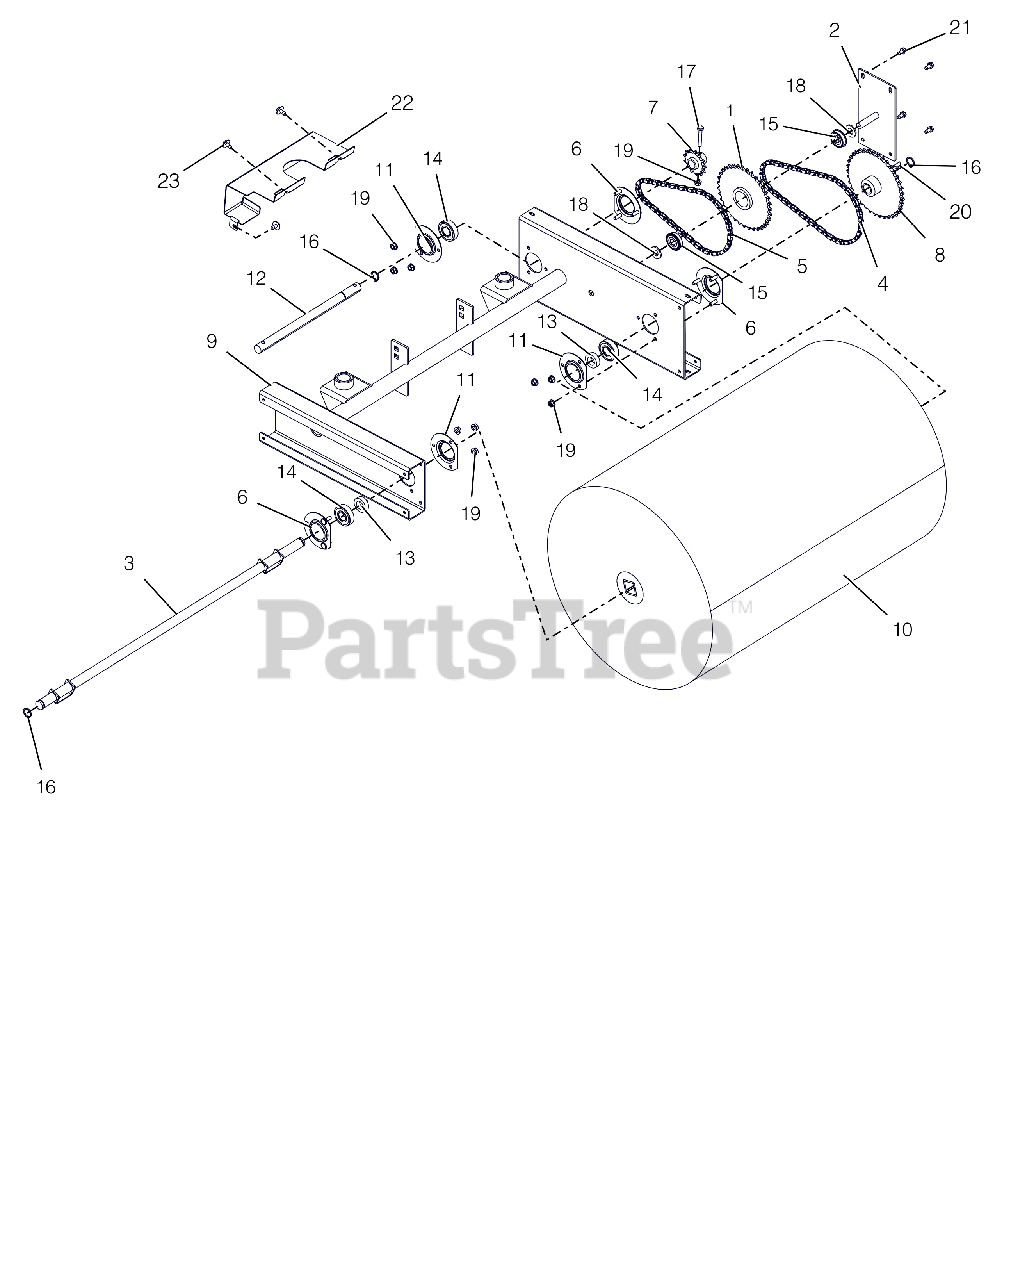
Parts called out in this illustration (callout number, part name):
1	SPROCKET, REDUCTION IDLER
2	PLATE, IDLER REDUCTION MOUNT
3	SHAFT, 28" BRUSH
4	CHAIN, #40-54 LINKS
5	CHAIN, #41-50 LINKS
6	BEARING FLANGE
7	SPROCKET, DRIVE
8	SPROCKET, DRIVEN
9	FRAME, POWER BROOM-DELUXE
10	BRUSH, 18"DIA X 28"WIDE
11	BEARING FLANGE
12	SHAFT, TRANSMISSION
13	SPACER .755X1.250X.370
14	BRG-BALL .750X1.750X.50
15	BRG-BALL .50X1.38X.438 SEALED
16	RG-RTNG-EXT .689X.078
17	@BLT-HEX .25-20X1.75 GR5 YWZC
18	WSHR-FL-STL .536X1.07X.109 YZ
19	@NUT-LK-TOP-FLG .25-20 YWZC
20	KEY-WDRF .188X.75X.313 SAE 9
21	SCR-TAP .25-20X.50 HWH TR YWZ
22	COVER, FRONT SHAFT - CE
23	SCR-TAP .25-20X.50 LGHWH TR YZ
